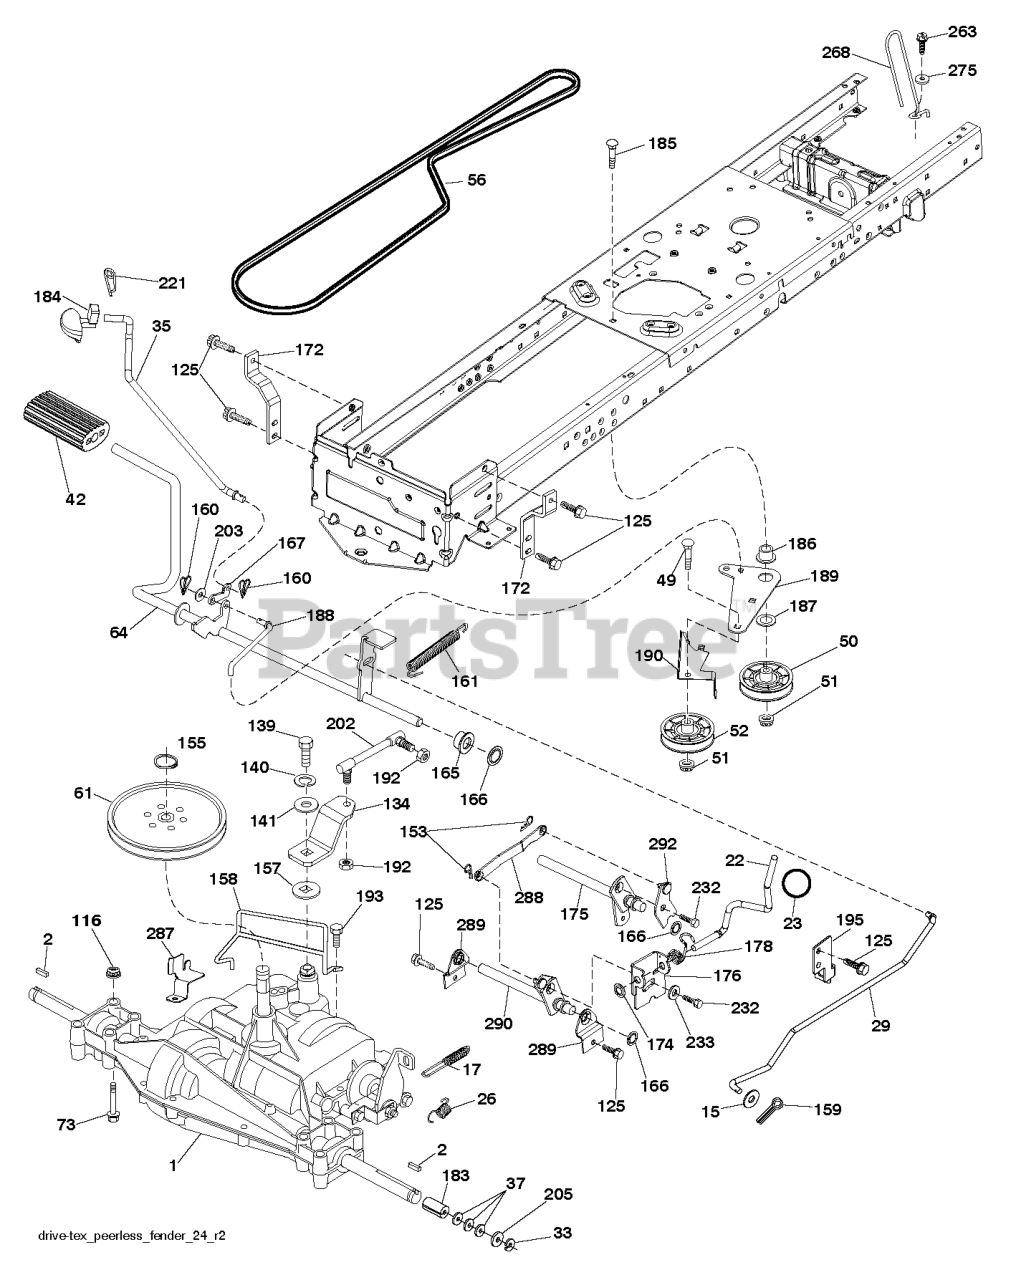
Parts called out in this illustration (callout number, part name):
2	SQUARE KEY
15	WASHER
17	SPRING.BRAKE.PEERLESS.TEX
22	SHIFTER.ASM.HANDLE.SRD
23	KNOB.DUCKHEAD.1/2
26	SPRING.BRAKE.RTN.GR.DR
29	ROD.BRAKE.PEERLESS
35	ROD.CNTRL.PARK.PREDATOR.LT.TEX
42	PEDAL COVER T
50	IDLER.FLAT.910.OFFSET
51	NUT LOCK FLG 3/8-16 UNC
52	IDLER.V-GROOVE.910.OFFSET
56	BELT, V GROUND DRIVE 95 25
61	PULLEY
64	SHAFT.ASM.PEDAL.BRAKE.
73	BOLT
116	NUT LOCK HEX FLANGE 5/16-18
125	SCREW
139	BOLT 1/4-28X3/4
140	LOCKWASHER
141	WASHER LT
153	RETAINER M
155	RETAINING RING LT
157	WASH-SHFT PLT LT
158	KEEPER.PMS.18/20.D4365
159	COTTER PIN
160	RETAINER CLIP
161	SPRING, RETURN LT
165	BUSHING.SHAFT.BRAKE.HAND
166	NUT.PUSH.625
167	LATCH.BRAKE.SPRING
172	STRAP.TRQ.LH.GEAR.DRIV
174	NUT.PUSH.500.2006
175	SHAFT ASM SHIFT
176	ARM.CLEVIS.ROD.SHIFT
178	SPRING.TORSION.LIFT.HANDLE
183	SPACER AXLE
184	HANDLE.PARKING.BRK.PRED.LT.RED
186	SPACER.RETAINER
187	WASHER 12/32X2X10GA
188	RP.LINK.CLUTCH.GROUND.DRIVE
189	BELLCRANK.GROUND.DRIVE.TEX.
190	KEEPER.BELLCRANK.DRIVE
192	NUT LOCK CENTER 1/4 -28 FNTHD
193	SCREW 5/16"
195	BRKT.ROD.BRAKE.PEERLES
202	LINK.SHIFT.PMST.18" (SPG1286)
203	WASHER
221	RETAINER.SPRING.CLIP.H
232	BOLT FIN HEX 7/16-14 X 1
233	WASHER SERRATED
263	SCREW, 3/8-16X3/4
268	GUARD MUFFLER
275	WASHER
287	KEEPER.PULLEY.T/A.7.04
288	LINK.SHIFT.SLAVE.SRD
289	BRACKET.SUPPORT.SHIFT.OUTER
290	SHAFT.ASM.SHIFT.REAR.SRD
292	PLATE.ASM.SHIFT.FWD.SRD
